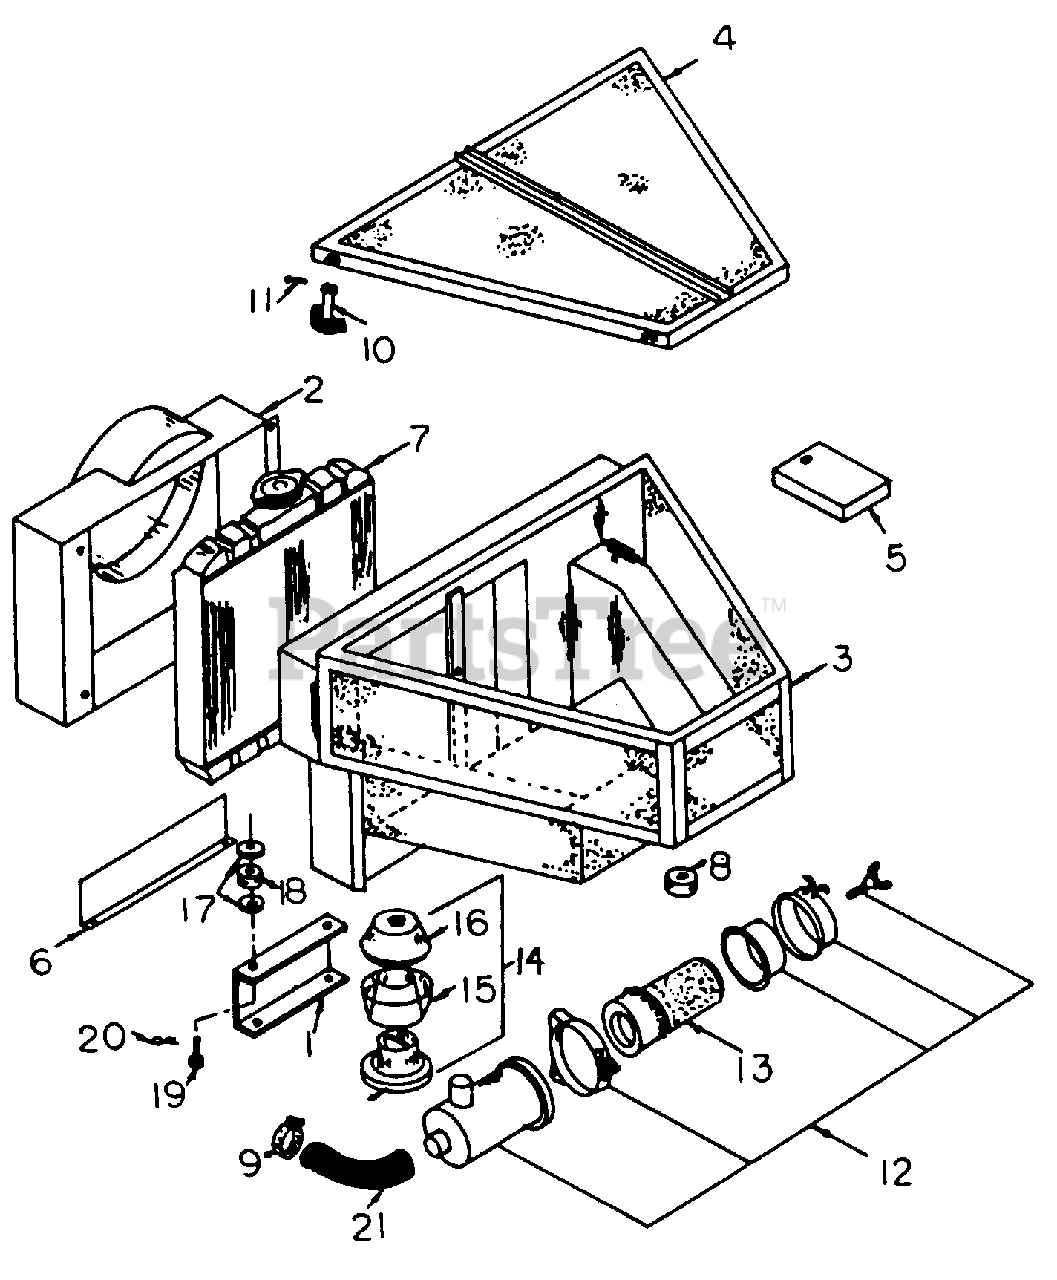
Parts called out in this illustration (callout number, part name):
1	Radlator Spaclng, 3 Cyl Only
2	Fan Shroud, 4 Cyl
3	Air Intake, Radiator 1
4	Air Intake, Lid
5	Air Intake, Axle Cover
6	Flll Plate, 3 Cyl
7	Radiator, 4 Cyl
9	Hose Clamp, l" to 2"
10	Rubber Hold Down
11	Rubber Hold Down Pln
12	Air Cleaner Assembly
13	Air Cle-ner Element
14	Precleaner Assembly
15	Prccleaner Bowl
16	Precleaner Lid
17	Rubber Pad Washer
18	Rubbr Pad
19	Ratlator Bolts
20	Hair Pins, Rad. Bolts
21	Air Cleaner Hose
